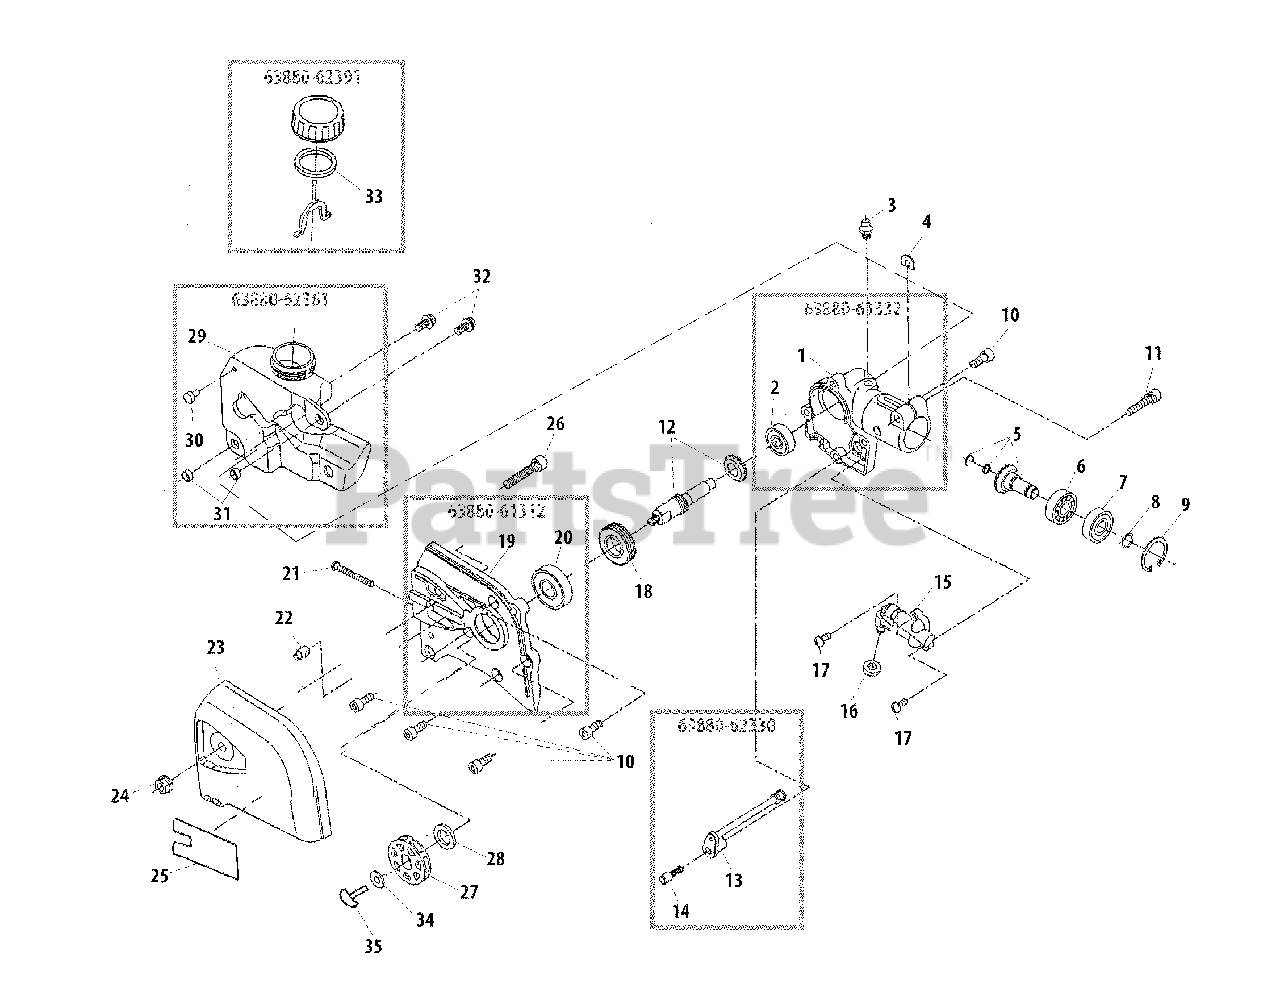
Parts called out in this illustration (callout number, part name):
1	CASE, GEAR - RIGHT
2	BEARING, BALL - 627ZZ
3	FITTING, GREASE
4	SHIM
5	GEAR - BEVEL
6	BEARING, BALL - 609
7	BEARING, BALL - 609ZZ
8	RING, RETAINING
9	RING, RETAINING - 24
10	SCREW - 5X12
11	SCREW - 5X25
12	GEAR - SHAFT
13	PIPE - OIL
14	FILTER
15	AUTO-OILER ASSY
16	GASKET, PUMP
17	SCREW - 4X10
18	GEAR - WORM
19	GEAR CASE ASSY - LEFT
20	BEARING, BALL - 6001DDU
21	SCREW - 4X35
22	TENSIONER, CHAIN
23	COVER
24	NUT - 6 -- FLANGE
25	LABEL - CAUTION
26	SCREW - 6X30
27	SPROCKET
28	COLLAR
29	TANK, OIL
30	VALVE, OIL
32	SCREW - 5X12
33	GASKET, CAP
34	WASHER - 6
35	SCREW - 6X14
63880-61312	GEAR CASE ASSY - LEFT
63880-61332	GEAR CASE ASSY - RIGHT
63880-62330	OIL TUBE ASSY
63880-62361	OIL TANK ASSY
63880-62391	OIL CAP ASSY
